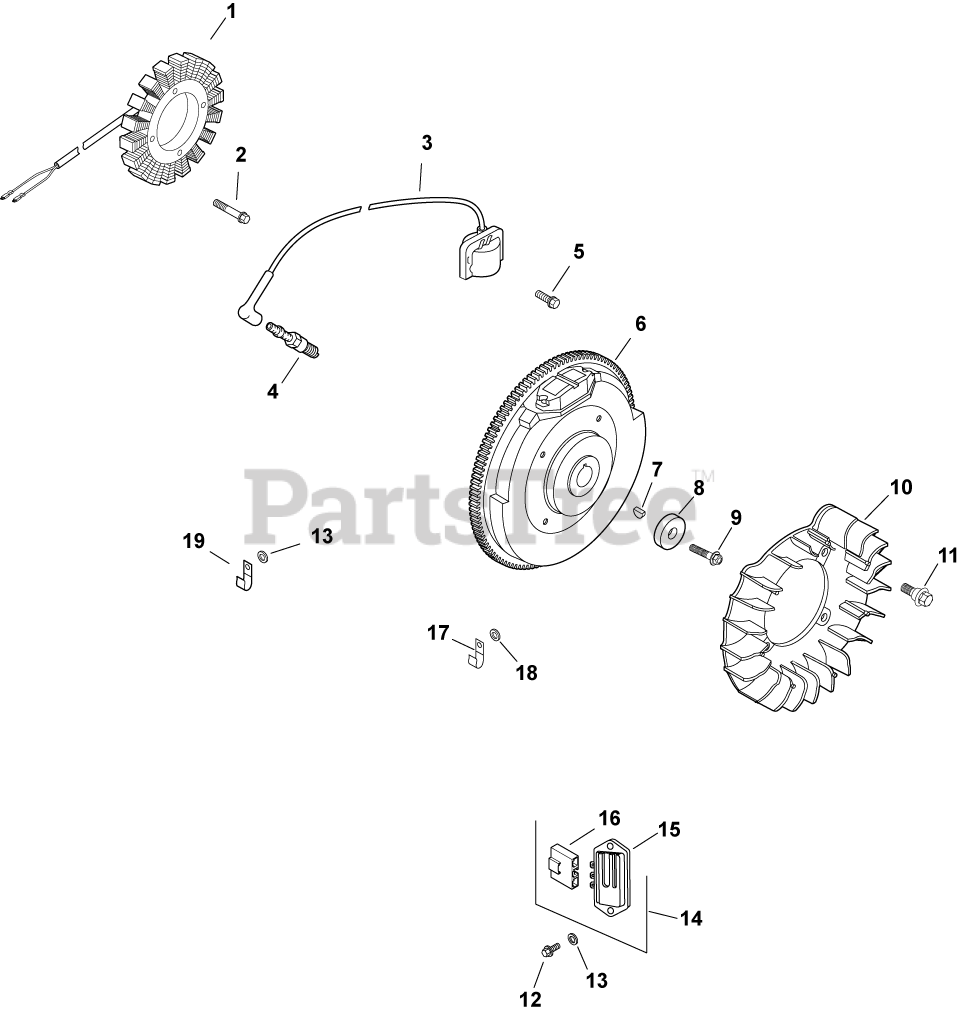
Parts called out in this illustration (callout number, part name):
1	KIT, 25 AMP STATOR ASSY.
2	SCREW, THD FROM M5X0.8X30
3	KIT, MODULE IGNTN (CDI FIXED)
4	PLUG, SPARK (STD)
5	SCREW, FLG THD FRM M5X.8X20-(#25086399S)
6	FLYWHEEL, PAINTED-USE 24 025 55-S
7	KEY, 3/16" X 5/8"
8	WASHER, FLAT 13/32"
9	SCREW, FLG M10X1.5X45 - (#25086361S)
10	FAN (KM)-USE 24 157 15-S
11	BOLT, SHOULDER
12	SCREW, PHL HD #11-16X7/8"
13	WASHER, FLAT 7/32"
14	KIT, FULL WAVE CONVERSION
15	REG/RECTIFIER (20/25 AMP)-USE 25 403 20-
16	CONNECTOR, BODY (KM)-USE 25 155 41-S
17	CLIP, TUBE & WIRING (KM)
18	WASHER, FLAT 1/4" (O.D. 1/2")
19	CLIP, CABLE
